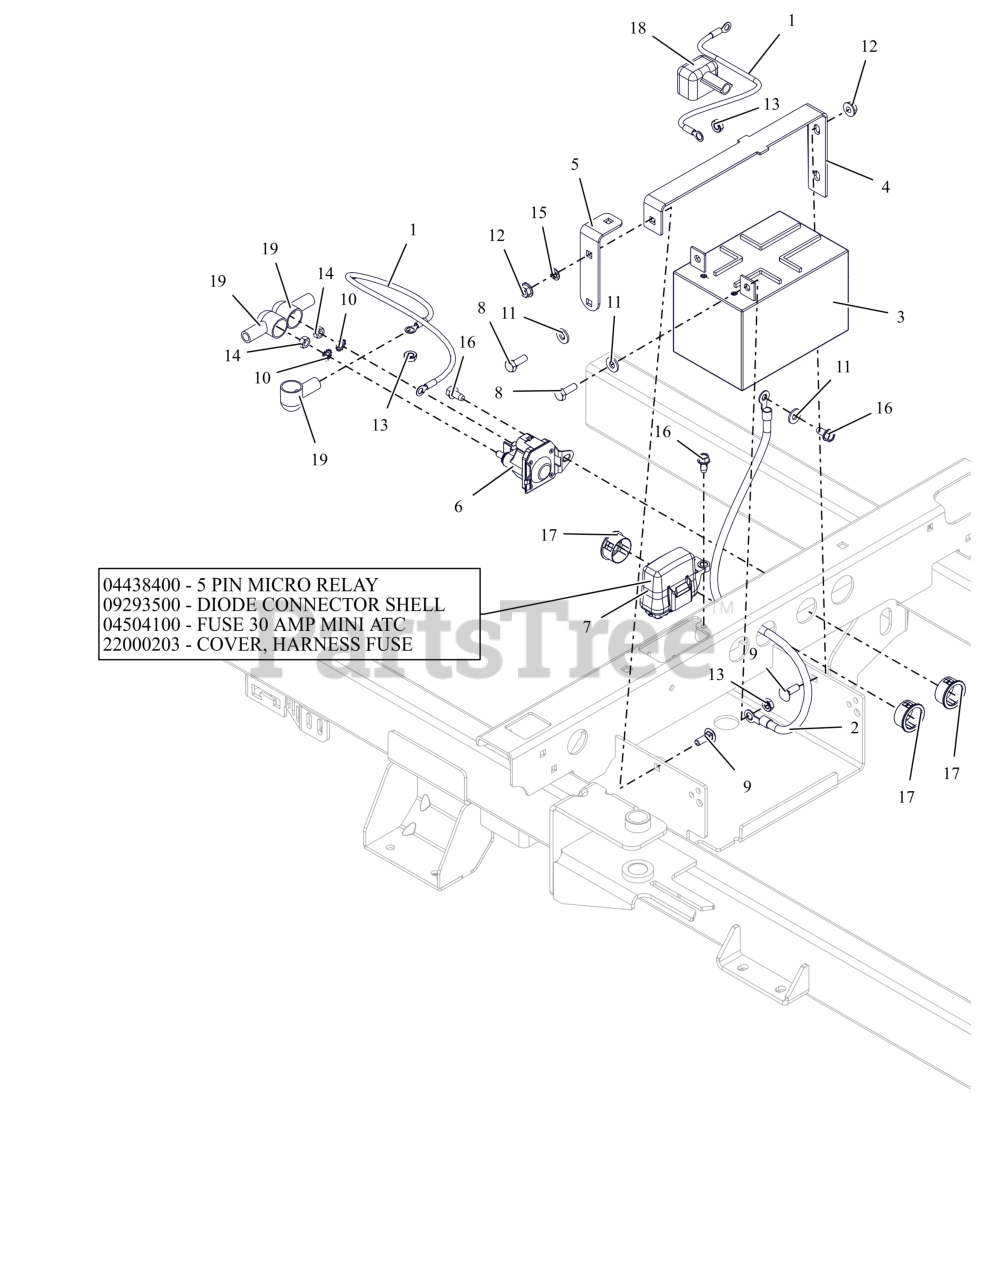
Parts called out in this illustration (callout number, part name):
1	CABLE,POS W/2 1/4 RING 15.0 LG
2	CABLE-NEGATIVE BATTERY 24.00"
3	BATTERY, 12V 12A-190CCA
4	BRKT, BATTERY HOLD-DOWN
5	BRKT, BATTERY HOLD DOWN
6	SOLENOID, STARTER (SEALED)
7	HARNESS, WIRE
7	RELAY,MICRO5 TERML W/RESISTOR
7	DIODE, CONNECTOR SHELL
7	FUSE,30 AMP MINI-ATC
7	COVER, FUSE
8	BLT, HEX .25-20X.75 G5 ZCC
9	BLT, RHSN .25-20X.750 G5 ZCC
10	WSHR,LK-EXT.262X.502X.026 ZCC
11	WSHR,FLT .281X.625X.065 ZCC
12	NUT-LK-TOP-FLG .250-20 GF ZCC
13	NUT-KEPS .250-20 ZCC
14	NUT-STD M6-1.0 ZCC
15	NUT-PUSH .25X.50 O.D.
16	SCR-TAP .25-20X.50 HWH ZCC
17	BSHG, PANEL SNAP .937X1.11X.56
18	INSULATOR
19	BOOT, EYELET TERMINAL
